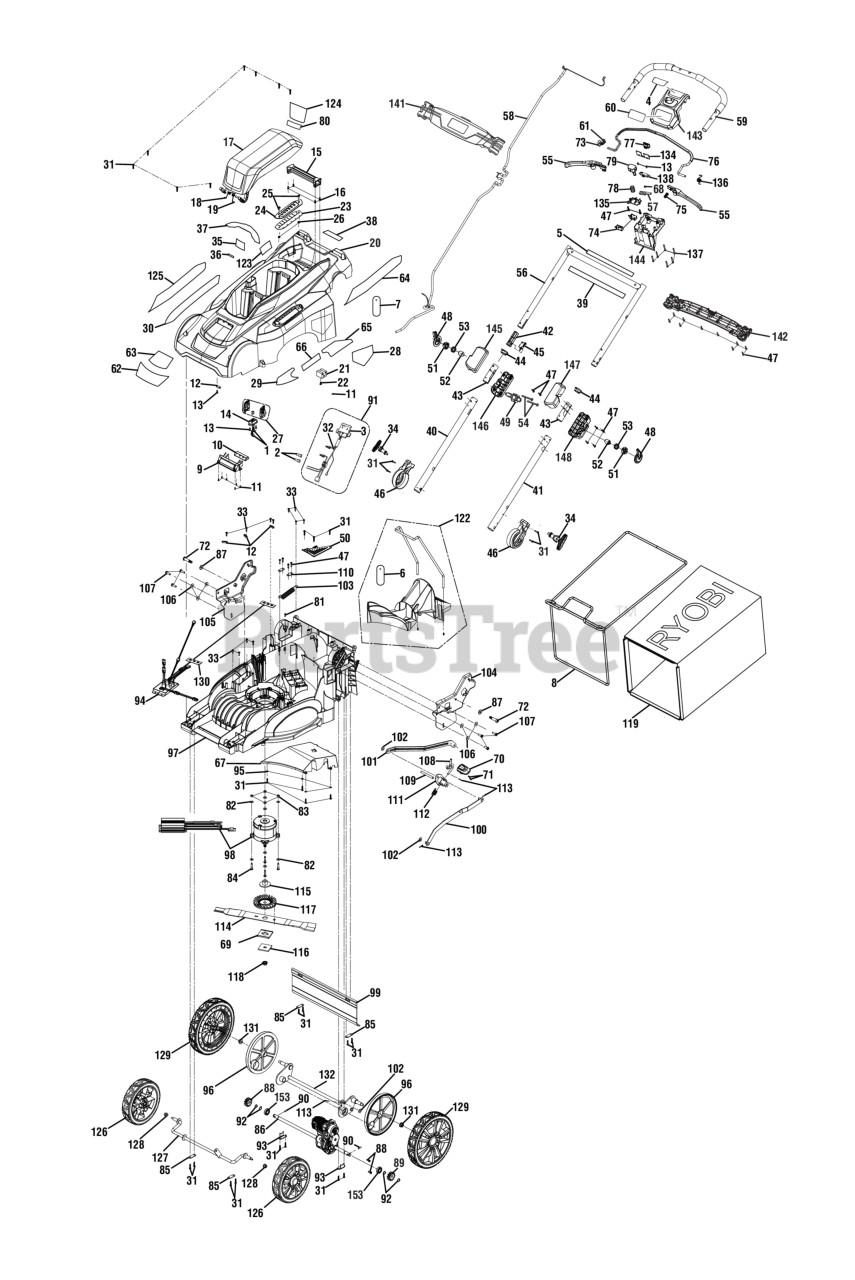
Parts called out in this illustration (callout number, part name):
1	Female Terminal
2	Close-End Connector
3	Battery Hold Assembly
4	Starting Instructions Label
5	Handles Fully Extended Label
6	Mulch Plug Hangtag
7	Start Key Hangtag
8	FRAME, 20 INCH GRASS BAG, BLACK
9	LED Cover
10	Light Reflector
11	Screw (M3 x 8 mm, Pan Hd., Pan Hd)
12	Wire Press Plate
13	Screw (M4.2 x 12 mm, T20 Torx Pan Hd.)
14	Key Holder
15	Carry Handle
16	Screw (M4 x 10 mm, T20 Torx Pan Hd.)
17	Battery Cover
18	Battery Door Right Torsion Spring
19	Battery Door Left Torsion Spring
20	Top Cover
21	SENSOR SWITCH FOR GRASS BAG
22	Screw w/Washer (M4 x 10 mm, T20 Torx Button Hd.)
23	Shifter Boot
24	Height Adjustment Plate
25	SCREW (M5 x 16 mm SOC. WASHER HD. CAP)
26	Lock Nut (M5 x 0.8 mm)
27	START KEY W/ HANG TAG
28	Danger Label (No Hands/Feet)
29	Front Green Accent Label
30	Side Green Accent Label
31	Screw (M4 x 20 mm, T20 Torx Pan Hd. S.T.)
32	Inner Wire with Terminal
33	Screw (M4 x 16 mm, T20 Torx Pan Hd.).
34	SPRING PIN ADJUSTMENT ASSEMBLY
35	Wet Conditions Warning Label
36	Onboard Battery Storage Label
37	Start Key Warning Label
38	Attachment User Callout Label
39	Handle Logo Label
40	STEEL TUBE,LOW RIGHT HANDLE TUBE
41	STEEL TUBE,LOW LEFT HANDLE TUBE
42	Switch Plug Housing
43	Handle Tube Bushing
44	Handle Tube Bushing (Small)
46	HINGE SHROUD
47	Screw (M4 x 18 mm, T20 Torx Pan Hd.)
48	Side Handle Latch
49	Press Plate
50	Transmission Cover Assembly
51	Disc Holder
52	Side Compression Disc
53	Handle Compression Spring
54	Screw (M4 x 38 mm)
55	TRIGGER ASSEMBLY
56	Upper Handle Tube Assembly (Inc. Key Nos. 5 & 39)
57	Cable Bracket
58	Inner Wire and Plug Assembly
59	Upper Handle Assembly
60	Handles Fully Extended Label
61	Actuator Switch
62	LABEL, FRONT ""BRUSHLESS""
63	Ryobi 40V Lithium Label
64	Brushless Label (Left)
65	Single Point Height Adjustment Label
66	Cut Height Label
68	Screw (M4x 7 mm, T20 Torx Hd)
71	Screw (M3 x 9 mm, Flat Hd.)
72	Screw (M8 x 33 mm, Hex Hd.)
73	Stop Switch (Momentary Contact)
74	On/Off Switch
75	Compression Spring
76	Bail Handle (Power Lever)
77	Thumb Pad
78	Safety Button Spring
79	Safety Button
80	Main Warning Label (Part 1)
81	Screw (M3 x 12 mm)
82	Washer (ID6.2 x OD15 x 0.08t)
83	Lock Nut (M6)
84	Bolt (M6 x 26 mm, Hex Hd.)
85	Axle Pressure Plate
86	Transmisson
87	Washer (ID8.5 x OD20.5 x 2 mm x 2t)
88	Drive Gear, Right
89	Drive Gear, Left
90	Drive Gear, Right
91	BATTERY HOLDER AND WIRE ASSEMBLY
92	Retaining Ring
93	Mounting Plate
94	Drive Motor Controller
95	Washer (ID4.5 x OD10 x 1t)
96	Wheel Cover
98	MOTOR 10035#, CONTROLLER ASSEMBLE,HUAJIE
99	Rear Protective Guard
100	Forward Linkage
101	Rear Lift Rod
102	Washer (ID8.4 x OD18 x 1t)
103	Rentention Spring
104	STAMPING, LEFT HANDLE BRACKET
105	STAMPING, RIGHT HANDLE BRACKET
106	Washer (1/4 in., Type A)
107	Screw (1/4-15 x 3/4 in., T30 Torx Pan Hd.)
108	Lever Arm
109	Axle (Height Adjustment)
110	Pressure Plate (Height Adjustment)
111	Height Adjustment Bracket
112	Torsion Spring (Height Adjustment)
113	Cotter PinÏ? (2.5)
114	Bagging Blade
115	Motor Shaft Bushing
116	Metal Blade Retainer
117	Motor Fan Blade Adapter
118	Blade Nut (M10 x 1.25, Hex Flange Hd.)
119	GRASS BAG
122	Mulch Plug Assembly (Inc. Key No. 6)
123	Data Label (RY401012)
124	Main Warning Label (Part 2)
125	Brushless Label (Right)
126	PLASTIC,8'' WHEEL ASSEMBLY
127	Front Axle
128	Flange Lock Nut (M8 x 1.25 mm)
129	PLASTIC, 10"" WHEEL ASSEMBLY
131	Lock Nut (3/8-16, Flange)
132	Rear Wheel Axle with rotation Plate
133	Ball Bearing (OD28.6 x ID12.7 x 8)
134	Dust Shield
135	Spring Holder
136	Torsion Spring
137	Screw (M4-18 x 30 mm, T15 Torx Soc. Hd.)
138	Variable Switch
139	Front Upper Handle Support
140	Rear Upper Handle Support
141	Front Upper Handle Support
142	Upper Handle Support (Rear Crossbar)
143	PLASTIC,FRONT UPPER HANDLE SUPPORT, ABS
144	Upper Handle Support (Rear)
145	Handle Latch (Right Front Housing)
146	Rear Housing Handle Latch (Right)
147	Front Housing Handle Latch (Left)
148	Rear Housing Handle Latch (Left)
